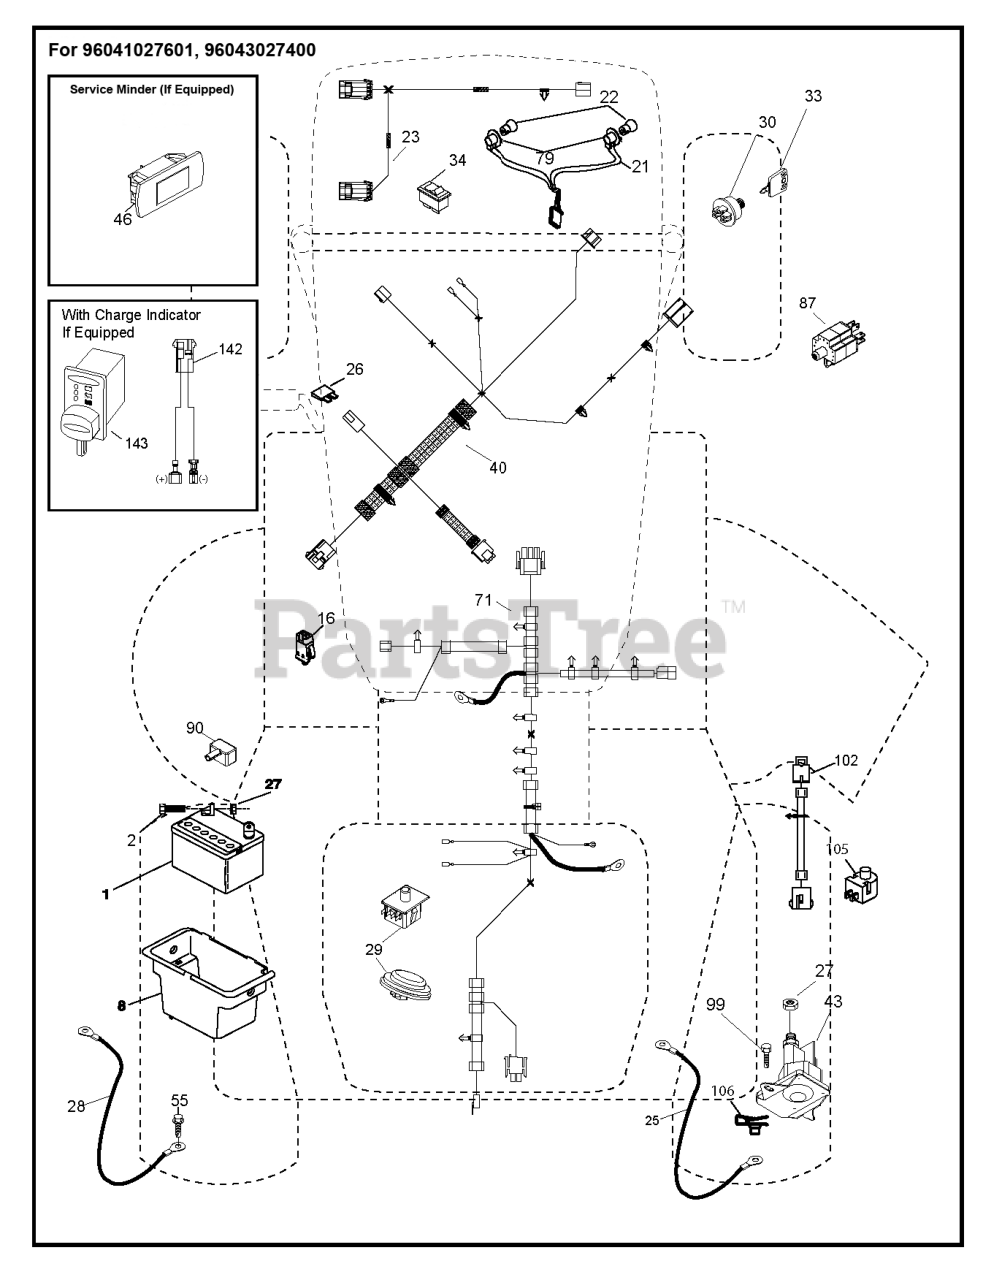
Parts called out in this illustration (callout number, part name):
1	Battery 12 Volt 25 Amp
2	BOLT.HEX.1/4.X.3/4.DICHROMATE
8	BOX.BATTERY.MNT.REAR.L
16	SWITCH INTERLOOK PUSH-IN
21	HARNESS.LIGHT W/4152J BULBS
22	LIGHTBULB
23	HARNESS LIGHT ASSY TRACTOR,
25	CABLE.BATT.RED.8GA.17
26	FUSE 20AMP
27	NUT
28	CABLE.GROUND.REAR.BATTERY.8G
29	SWITCH.SEAT.DELTA.OPC.
30	SWITCH.IGN.DELTA.W.LGH.ROS
33	KEY.CHAIN.BLISTER.PACK.GEN.USA
33	KEY.CHAIN.BLISTER.PACK.GEN.INT
40	HARNESS.TEX.DASH.MAN.REAR BATT
43	SOLENOID.STARTER.BRASS.PLUNGER
46	RP.GUAGE.SRVCMNDR.HRMTR.
46	GUAGE.SRVCMNDR.HRMTR.
55	SCREW 5/16"
71	HARNESS.CHASSIS.RRBATT.RDYSTRT
71	HARNESS.TEX.CHSSIS.REAR.BATT
79	BULB HOLDER ASM.
87	SWITCH.INTRLCK.CLUTCH.
90	COVER.TERMINAL.BATTERY
99	SCREW HEXWSHR 1/4-20X3/4
102	HARNESS PIGTAIL PCH TEX ROS
105	REVERSE SWITCH
106	1/4-20 U NUT
